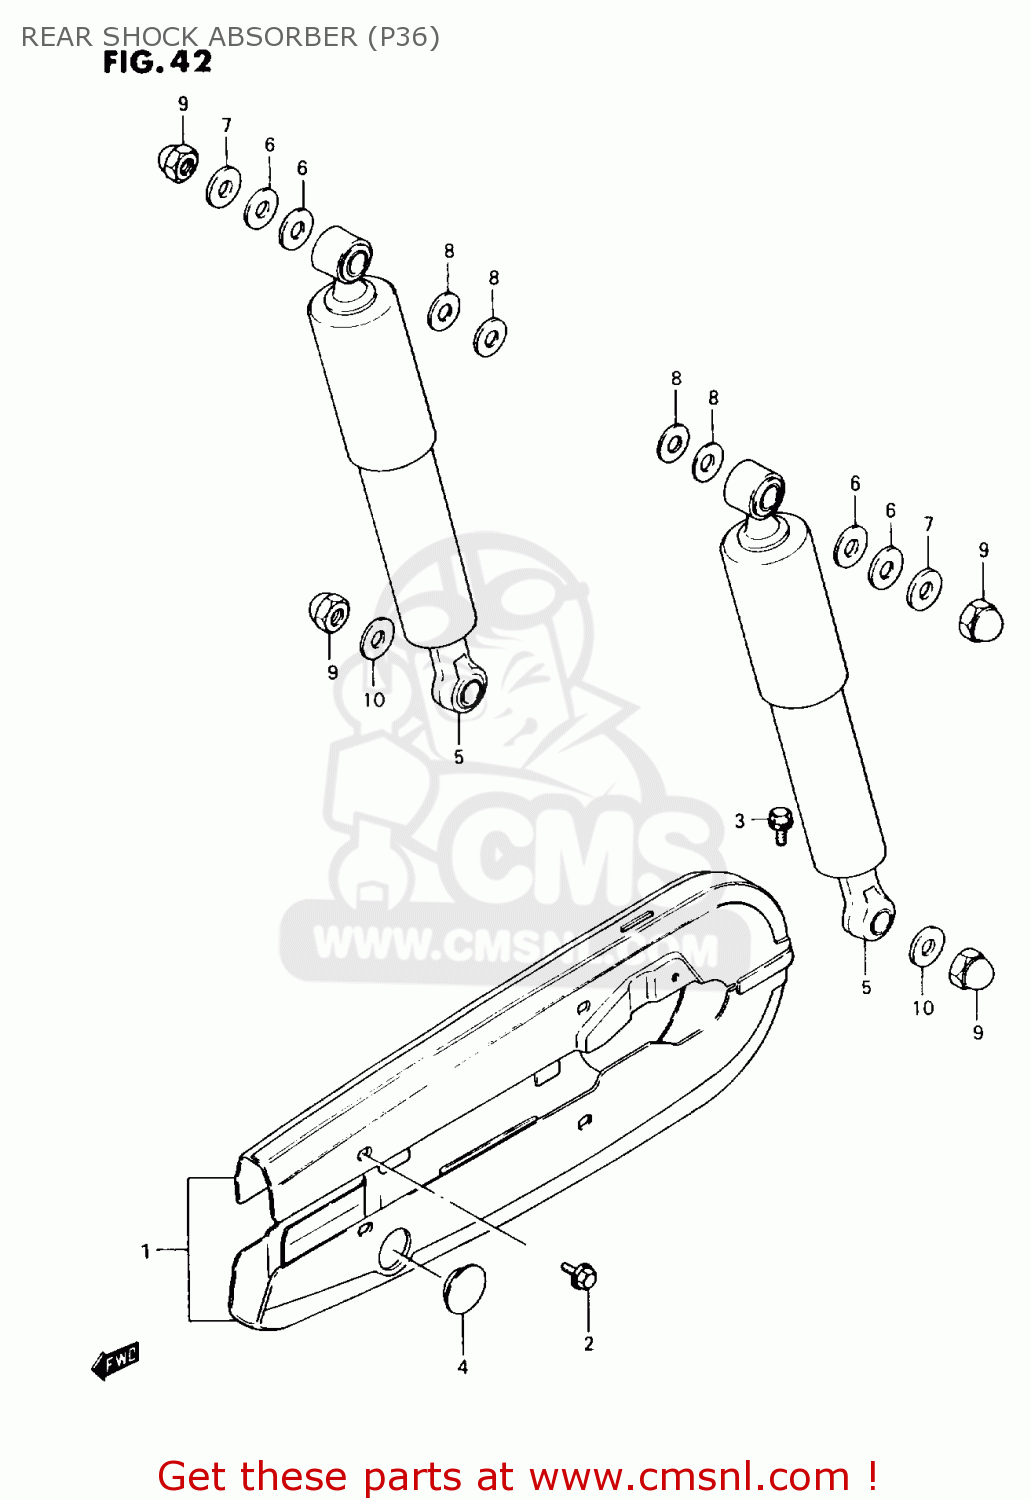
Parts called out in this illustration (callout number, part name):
1	CASE SET,CHAIN
2	BOLT(6X8)
3	BOLT(6X14)
4	CAP(OD:40)
5	ABSORBER, REAR SHOCK (RED)
6	WASHER
7	WASHER(10.5X24X3.2)
8	WASHER
9	NUT
10	WASHER(10.5X24X3.2)
